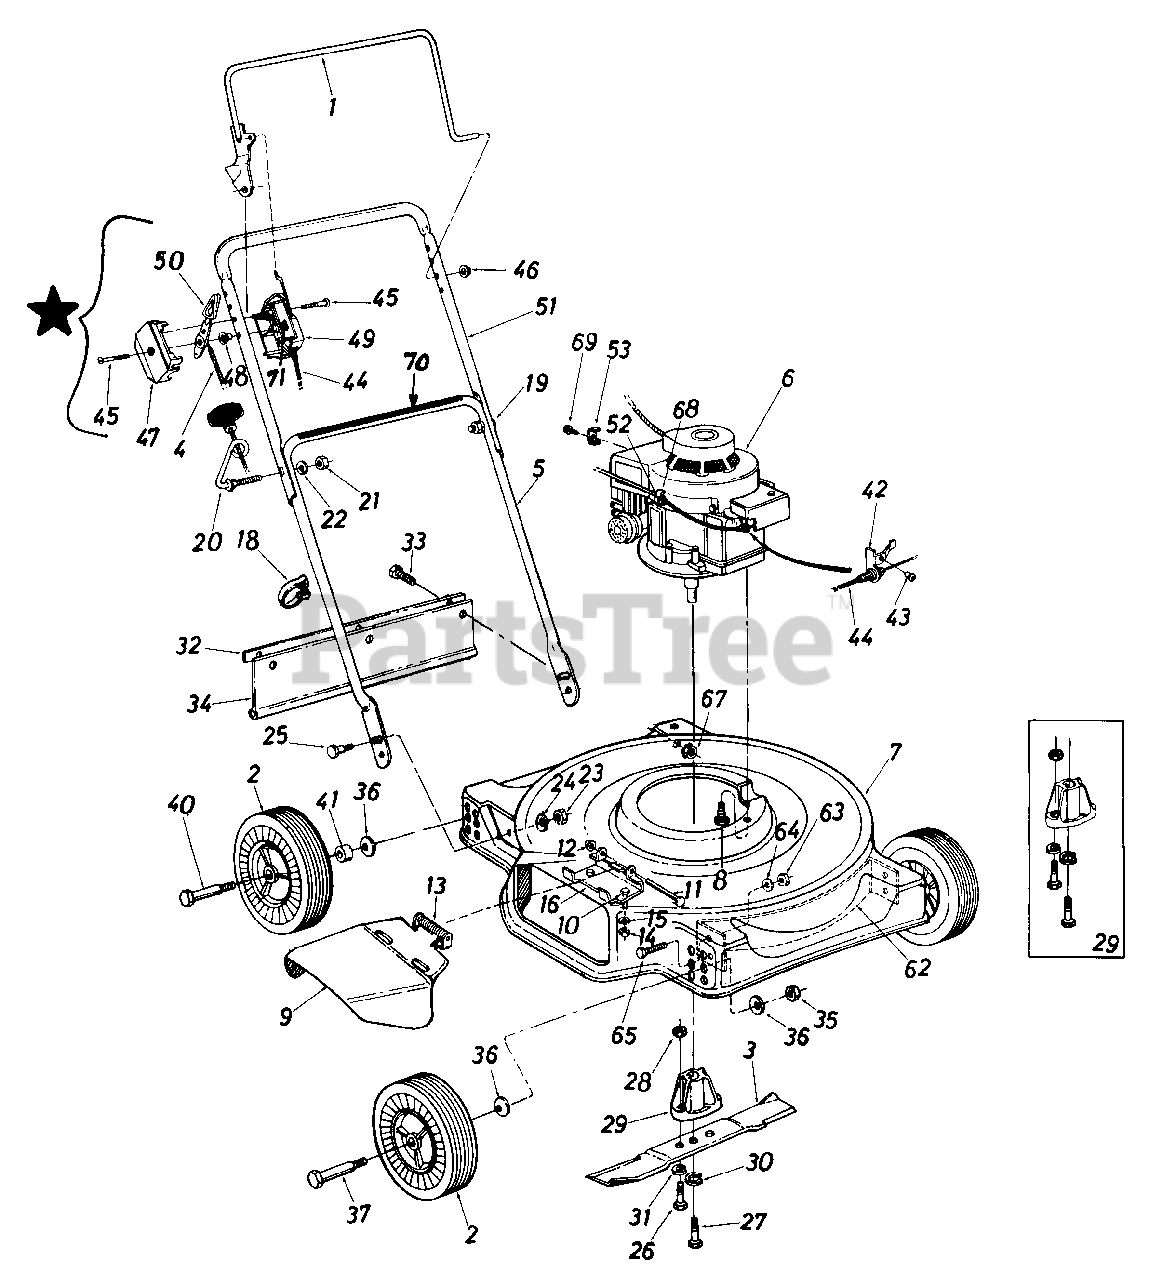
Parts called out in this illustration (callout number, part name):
1	Control Handle Ass'y. - R.H.
2	Wheel Ass'y. Comp.
3	20" Blade
4	Throttle Control Wire - 39.0"
5	Lower Handle
6	Engine
7	20" Deck Ass'y.
8	Hex Wash. Hd. TT-Tap Scr. 3/8-16 x 1.00" Lg.
9	Chute Deflector Ass'y.
10	Hex Bolt 1/4-20 x .50" Lg.
11	Hinge Pin 1/4" Dia. x 3.88 Lg.
12	Push Cap .25" Rod
13	Torsion Spring
14	Hex Nut 1/4-20 Thd.
15	L-Wash. 1/4" I.D.
16	Deflector Hinge Plate
18	Cable Tie
19	Curved Carriage Bolt 5/16-18 x 1.38" Lg.
20	Rope Guide Bolt
21	Hex Nut 5/16-18 Thd.
22	L-Wash. 5/16" I.D.
23	Hex Ins. L-Nut 5/16-18 Thd.
24	Bell-Wash. .345" I.D. x .88" O.D.
25	Shld. Bolt .437" Dia. x .268
26	Hex Bolt 5/16-24 x 1.00" Lg. (Grade 5) Special
27	Hex Bolt 3/8-24 x 2.25" Lg. (Grade 5)
28	Hex Nut 5/16-24 Thd.
29	Blade Adapter Kit
30	L-Wash. 3/8" I.D. - H.D.
31	L-Wash. 5/16" I.D.
32	Retainer Strip
33	Hex Bolt 1/4-20 x .62" Lg.
34	Rear Flap Ass'y.
35	Hex Nut 3/8-16 Thd.
36	Bell-Wash. .400" I.D. x .88" O.D.
37	Front Axle Bolt
40	Rear Axle Bolt
41	Spacer .511 I.D. x .70" O.D.
42	Cable Bracket
43	Pop Rivet .156" Dia. x .379
44	Control Cable 43" (Yellow)
45	Truss Mach. Scr. #12 x 1.50" Lg.
46	Cap Speed Nut 5/16" Rod
47	Control Panel Half
48	Control Disc Pin
49	Clutch Panel Half
50	Throttle Control Lever
51	Upper Handle
52	Hex "B" Tap Scr. #10 x .38"
53	Casing Clamp
62	20" Front Baffle
63	Hex Nut 3/8-16 Thd.
64	Bell-Wash..400 I.D. x .88 O.D.
65	Hex Bolt 3/8-16 x .62" Lg.
67	Hex Sems Nut 1/4-20 Thd.
68	Cable Clip
69	Hex "B" Tap Scr. #10 x .38"
70	Control Label-Handle
71	Control Label-Throttle
